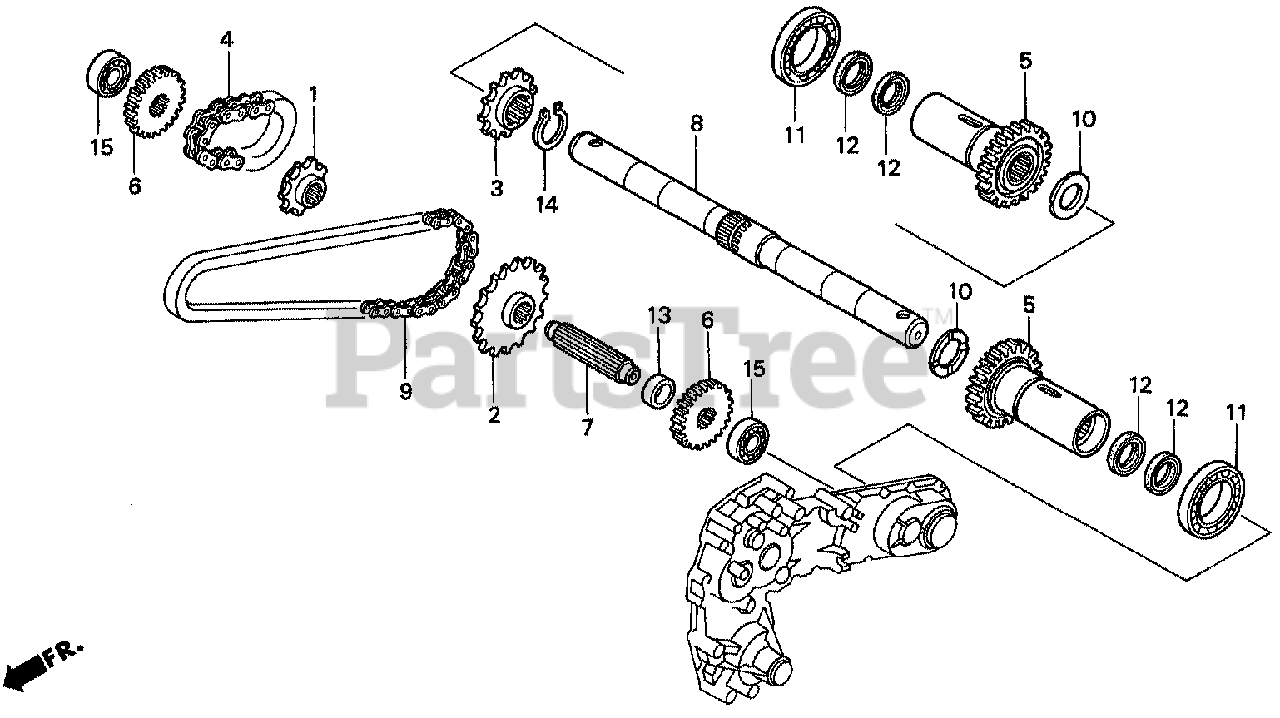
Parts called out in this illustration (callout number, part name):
1	SPROCKET, ROTOR REVERSE DRIVEN
2	SPROCKET, P.T.O. DRIVEN
3	SPROCKET, ROTOR REVERSE DRIVEN
4	CHAIN, P.T.O. REVERSE DRIVE
5	GEAR, ROTOR DRIVEN
6	GEAR, ROTARY DRIVEN
7	COUNTERSHAFT, ROTARY
8	SHAFT, ROTARY
9	CHAIN, ROTARY
10	WASHER, THRUST (25MM)
11	BEARING (40X62X12)
12	OIL SEAL (25X35X6)
13	COLLAR, ROTARY COUNTERSHAFT
14	CIRCLIP (OUTER) (30MM)
15	BEARING, RADIAL BALL (6202)
